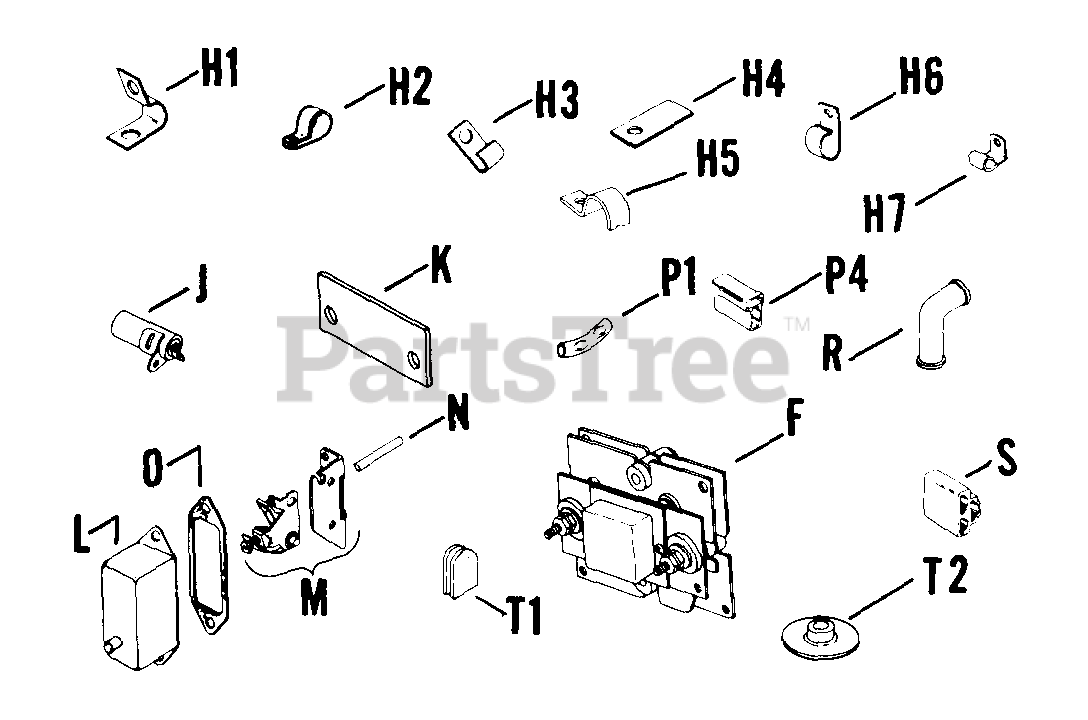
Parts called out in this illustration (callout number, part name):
H1	CLIP - USE 210281
H3	CLIP - USE 275303
J	CONDENSER
L	COVER - DISCONTINUED
M	BREAKER - USE 47 150 03
O	GASKET - USE 52 041 11
T1	GROMMET
